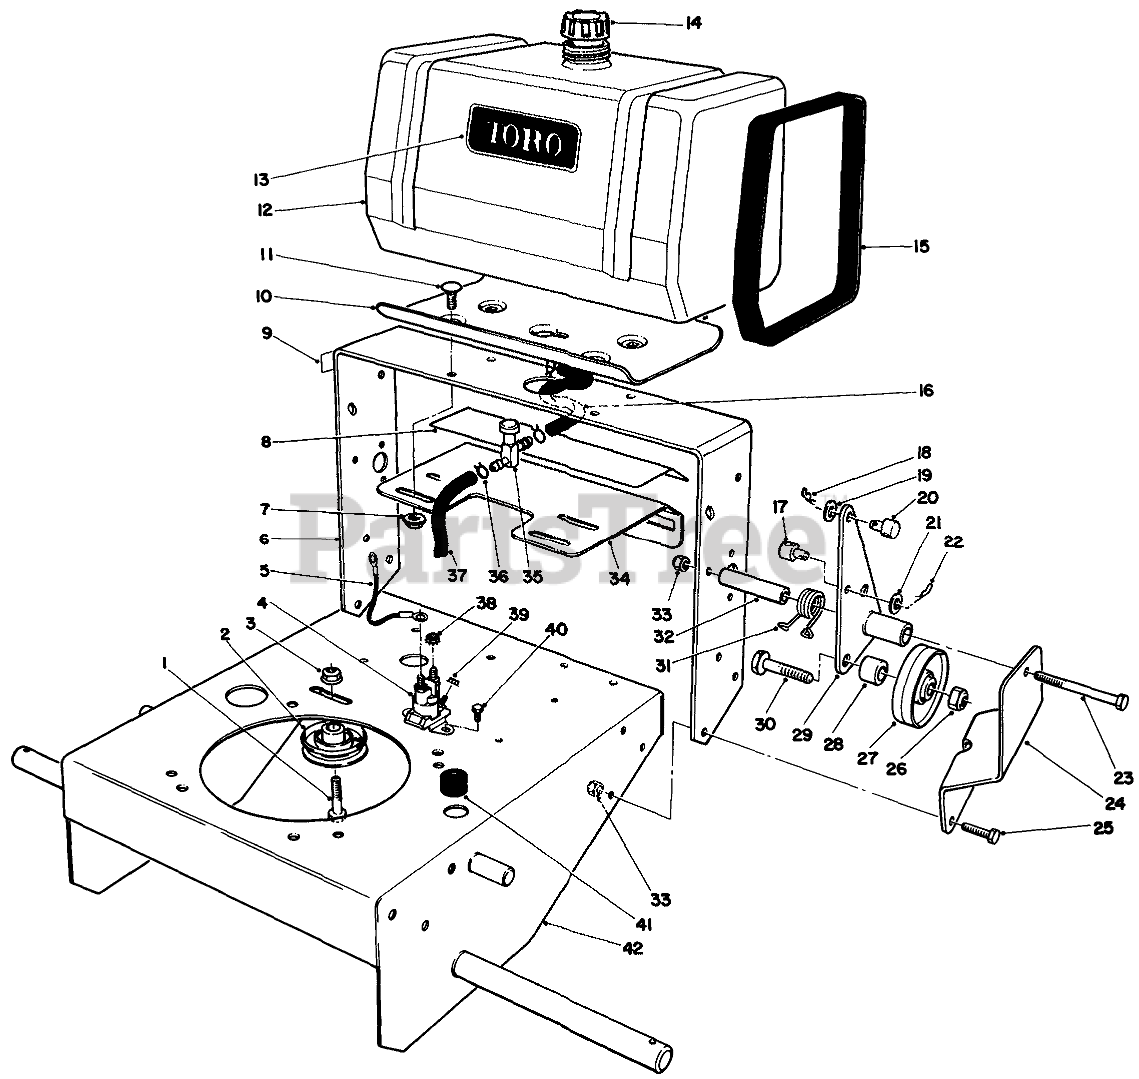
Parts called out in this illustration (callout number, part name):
1	SCREW-HH
2	PULLEY-IDLER
3	NUT-HF
4	Solenoid
5	WIRE-SOLENOID/STARTER
6	Frame-Rear
7	NUT-HF
8	Decal-Ground Speed
9	Decal-Fuel Shut Off
10	Plate-Fuel Tank
11	BOLT-CARR
12	Tank-Fuel
13	GAS TANK DECAL
14	GAS CAP ASM
15	Hinge-Seat
16	HOSE-FUEL
17	ROD FITTING
18	PIN-COTTER
19	WASHER-PLAIN
20	ROD FITTING
21	WASHER-PLAIN
22	PIN-COTTER
23	SCREW-HH
24	Support-Idler L.H.
25	SCREW-HH
26	NUT-LOCK, NI
27	IdlerWheel
28	WHEEL IDLER SPACER
29	LH IDLER BRKT WA
30	SCREW-LEVELER
31	SPRING-TORSION, LH
32	PIVOT-IDLER SPACER
33	NUT-LOCK, NI
34	CONTROL PLATE R
35	FUEL VALVE
36	Clamp
37	GAS HOSE
38	NUT-KEPS
39	NUT-KEPS
40	SCREW
41	GROMMET
42	Frame
